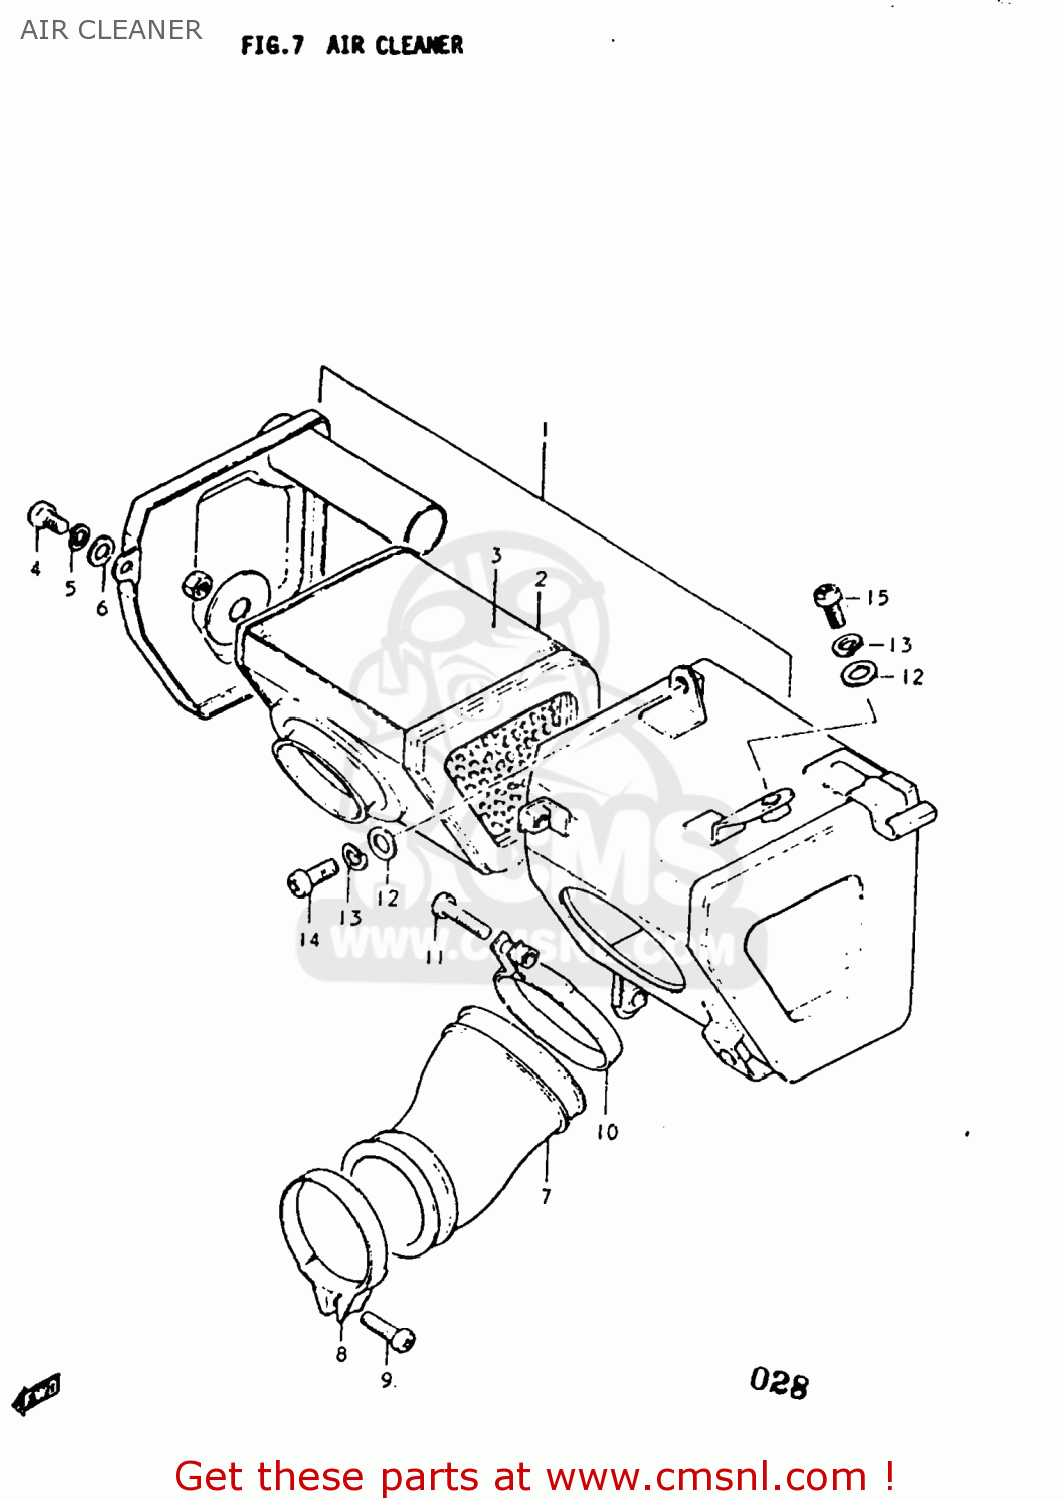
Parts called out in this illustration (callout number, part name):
1	CLEANER ASSEMBLY,AIR
2	FILTER,AIR CLEANER
3	FILTER
4	SCREW
5	LOCK WASHER
6	WASHER
7	TUBE,AIR CLEANER OUTLET
8	CLAMP
9	SCREW
10	CLAMP
11	SCREW
12	WASHER
13	LOCK WASHER
14	SCREW 6X12
15	SCREW
